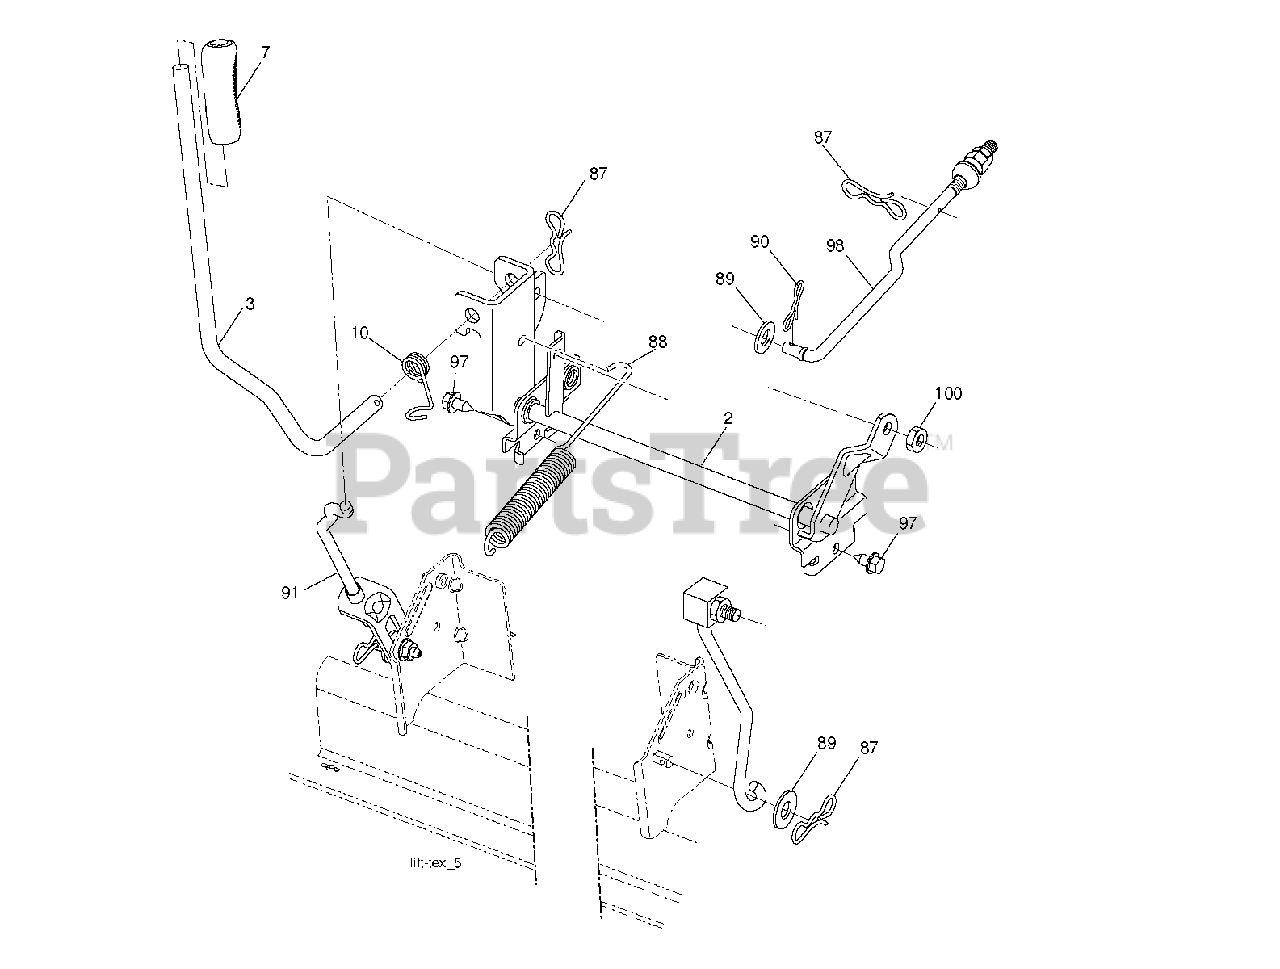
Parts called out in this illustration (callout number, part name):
2	SHAFT.ASM.LIFT.CROSS.H
3	LEVER.LIFT.HANDLE.LT
7	GRIP.HANDLE.LIFT.PVC.BLACK
10	SPRING.TORSION.LIFT.HANDLE
87	PIN.COTTER.7/16.BOW TI
88	SPRING.LIFT.ASSIST
89	WASHER.CLEAR.ZINC
90	PIN.COTTER.5/16.BOW TI
91	LINK.ASM.LIFT.REAR
97	SCREW, 3/8-16X3/4
98	LINK.ASM.SUSP.FRONT.MW
100	LOCKNUT
